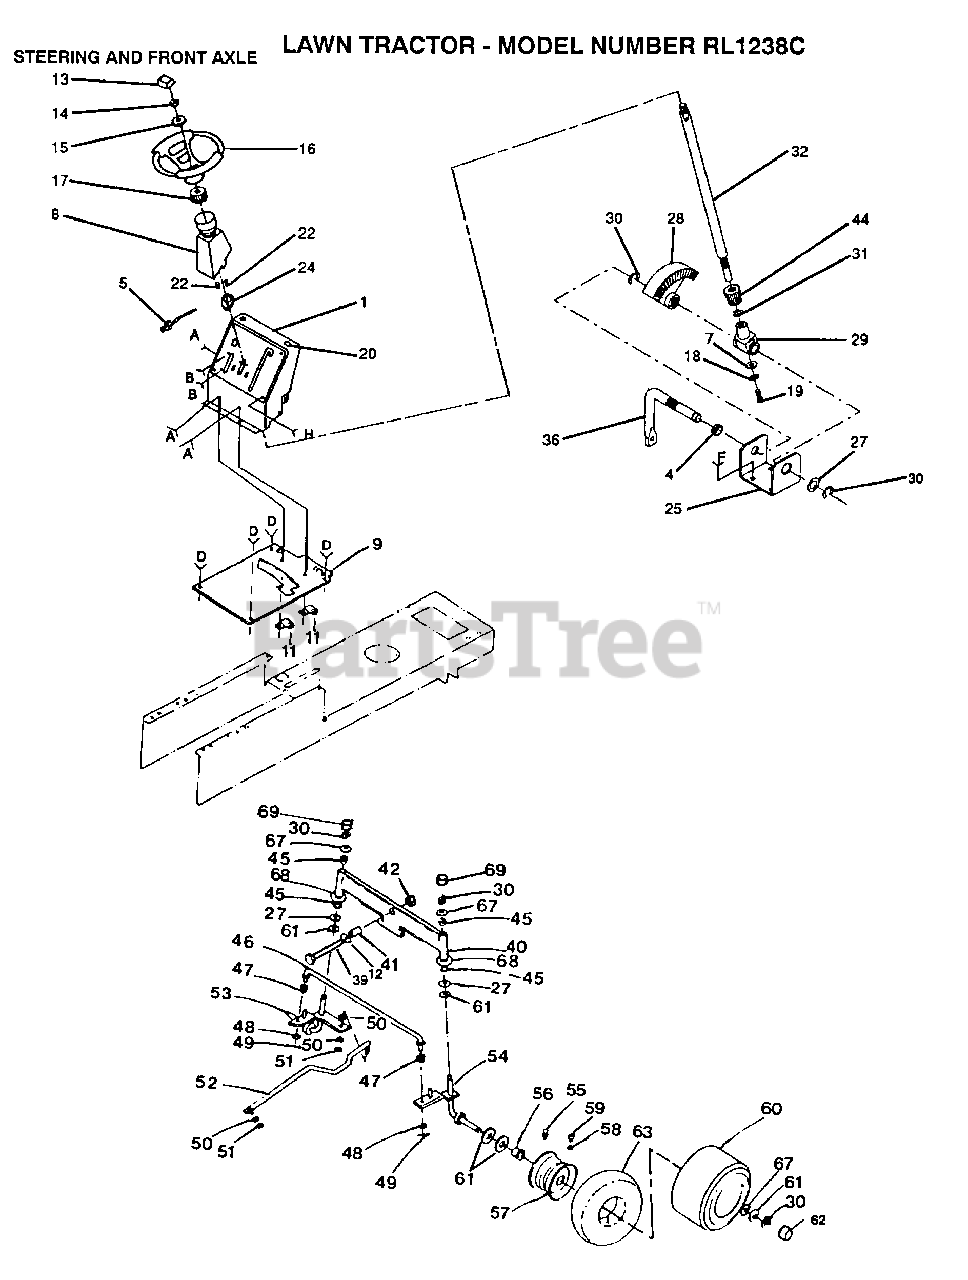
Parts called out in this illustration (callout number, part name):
2	SCREW
4	NYLINER T
6	SCREW LT
8	"TUBE, STR SHAFT"
10	SCREW LT
11	CLIP T
13	INSERT-WHEEL LT
15	WASHER
17	ADAPTER LT
18	LOCKWASHER
19	"SCREW,SPECIAL"
24	"BUSHING,STEERING"
25	"BRKT,STEERING"
26	SCREW
27	WASHER .T
29	SUPPORT.SHAFT
30	RING
31	THRUST WASHER
39	BOLT LT
41	BEARING
42	"NUT-LOC,FLANGE LT"
44	"GEAR,PINION"
45	COL. SRTG. BEAR.
48	WASHER
49	COTTER PIN
50	LOCKWASHER
53	SPINDLE-LH LT
55	FITTING LT
56	"FLANGE, BEARING"
58	VALVE CAP
59	VALVE STEM LT
61	WASHER
62	HUB CAP
63	TUBE.5.3/4.5/6
67	WASHER
68	WASHER
69	CAP
70	SCREW SPECIAL
